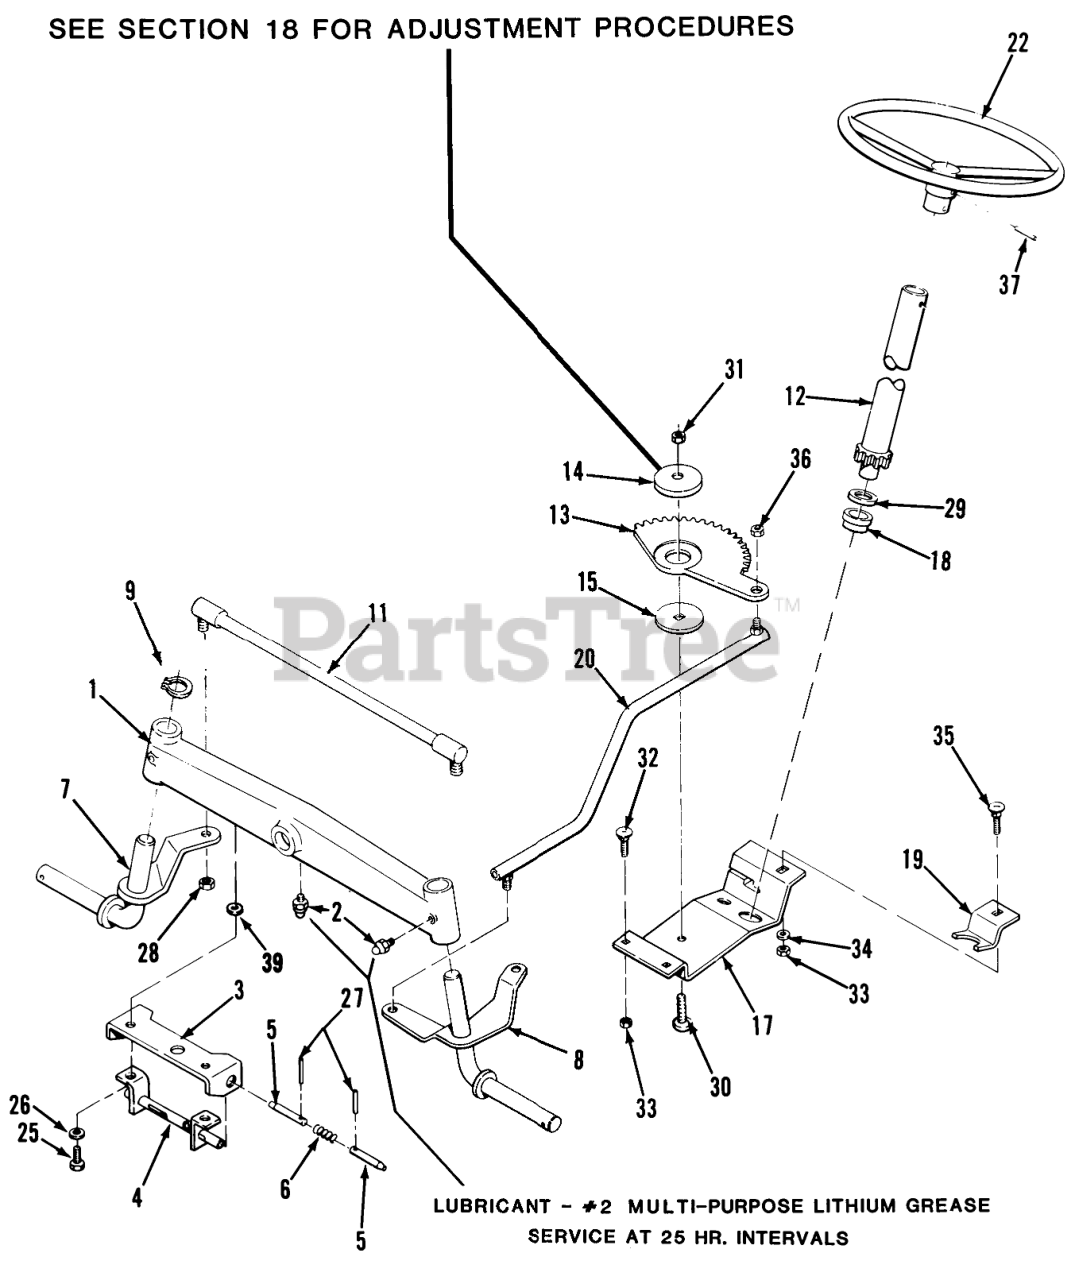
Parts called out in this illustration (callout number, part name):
1	Axle-Front
2	Zerk
3	BRACKET-SUPPORT R
4	TUBE & BRACKET ASM R
6	SPRING
7	ASSY ARM STEERING R
8	ASSY ARM STEERING R
9	Snap Ring
11	ASS'Y-TIE ROD R
12	ASSY PINION & SHA B
13	GEAR SECTOR
14	BUSHING
15	WASHER-BEARING
17	BRKT-STEERING GEAR
18	BEARING-WHEEL
19	RETAINER R (NS)
20	ASSY BALL JOINT L R
22	WHEEL STEERING
25	HHCS
26	Lockwasher
27	SPIROL PIN
28	Nut-Lock
29	WASHER
30	Bolt-Carriage
32	Bolt
33	Nut
34	WASHER 5/16 SAE
35	Bolt-Carriage
36	NUT-6
37	SPIROL PIN 5/16X13/8
39	WASHER
